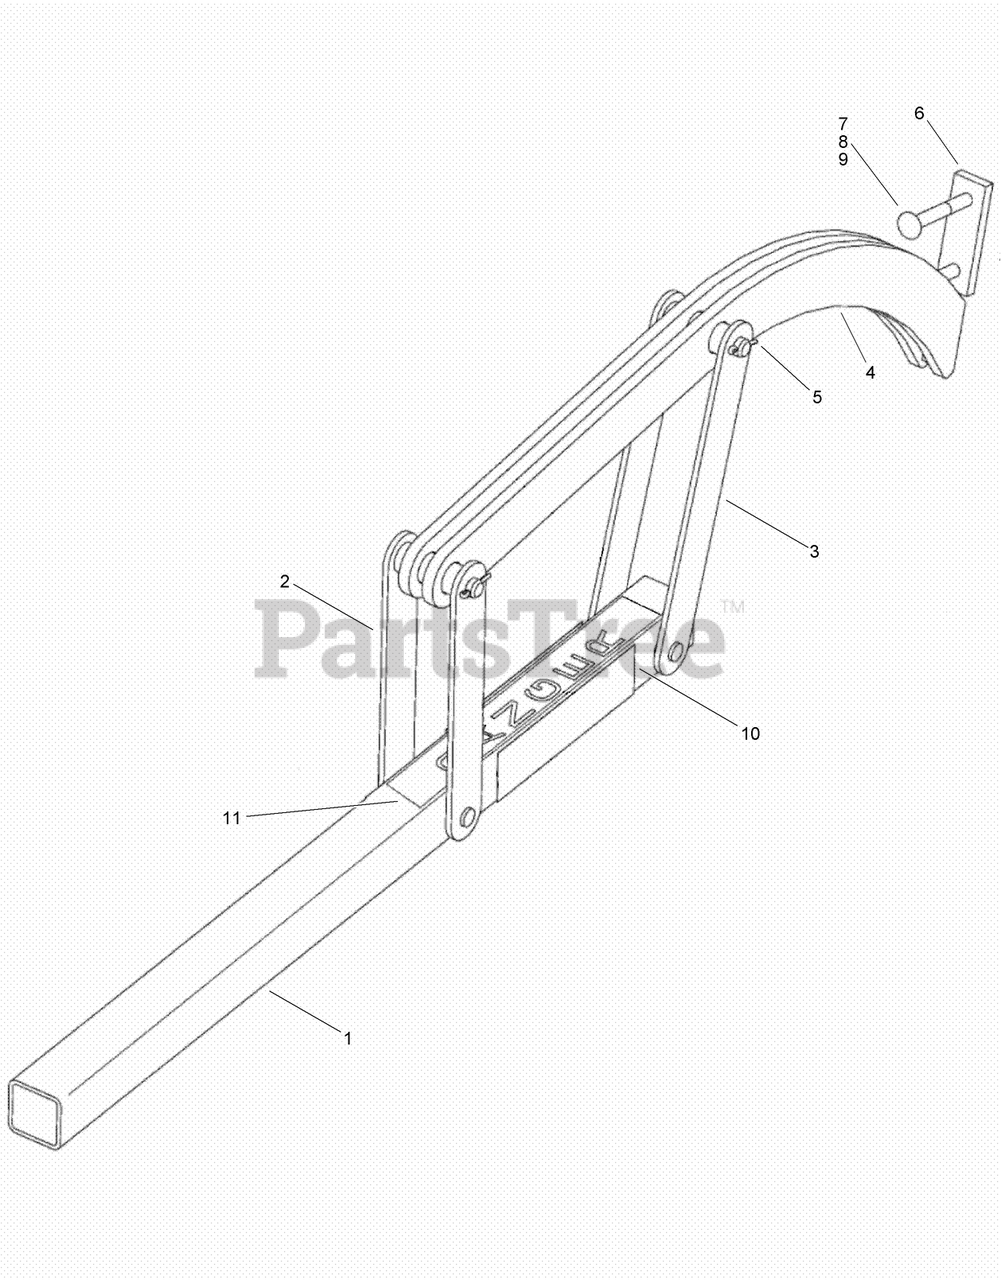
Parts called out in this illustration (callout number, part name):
1	TUBE-5 Foot Crumber
2	LINK-Crumber
3	LINK-boom to crumber, long
4	BLADE-Crumber
5	PIN-cotter, 3/16 x 1-1/4 inch
6	PLATE-spacer, bracket to blade
7	BOLT-CARR
8	WASHER-0.531 x 1.062 x 0.092 in CST ZND
9	NUT-LOCK, HEX
10	DECAL-Danger, Entanglement Hazard
11	DECAL-Danger
